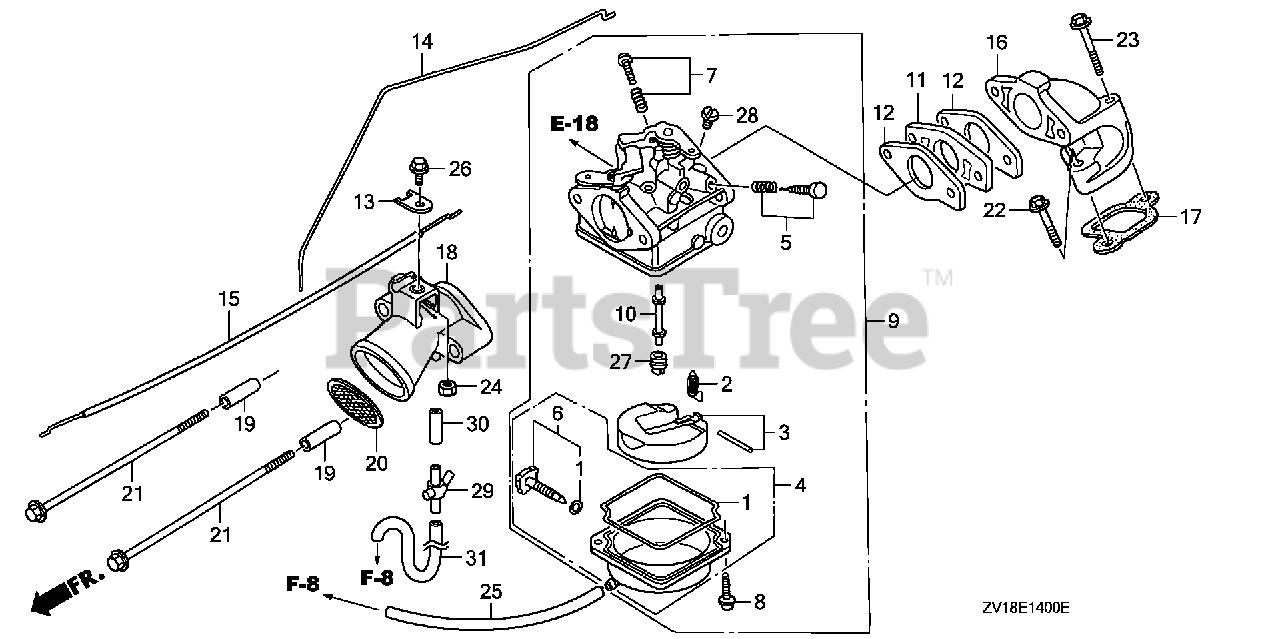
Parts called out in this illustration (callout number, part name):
1	GASKET SET
2	VALVE SET, FLOAT
4	CHAMBER SET, FLOAT
5	SCREW SET (CARBURETOR NO.)
6	SCREW SET, DRAIN
6	SCREW SET, DRAIN (CARBURETOR NO.)
8	SCREW, PAN
9	CARBURETOR ASSY. (BC05E D)
10	NOZZLE, MAIN (CARBURETOR NO.)
11	INSULATOR, CARBURETOR
12	GASKET, CARBURETOR
13	HOLDER, CABLE
14	ROD, THROTTLE
15	CABLE, CHOKE
16	MANIFOLD, IN.
17	GASKET, IN. MANIFOLD
18	GUIDE, AIR
19	COLLAR, DISTANCE
20	TRAP, FLAME
21	BOLT, FLANGE (6X102)
22	BOLT, FLANGE (6X28) (CT200)
23	BOLT, FLANGE (6X42)
24	NUT, HEX. (6MM)
25	BULK HOSE, VINYL (3.5X6.5X8000) (9500(95003-05001-60M) (CARBURETOR NO.)
26	BOLT, FLANGE (6X12)
27	JET, MAIN (#75) (CARBURETOR NO.)
27	JET, MAIN (#72) (CARBURETOR NO.)
27	JET, MAIN (#70) (CARBURETOR NO.)
27	JET, MAIN (#68) (CARBURETOR NO.)
29	JOINT, THREE WAY
30	BULK HOSE, VINYL (4X7X8000) (95003-07(95003-07001-60M) (CARBURETOR NO.)
31	BULK HOSE, VINYL (4X7X8000) (95003-07(95003-07001-60M) (CARBURETOR NO.)
